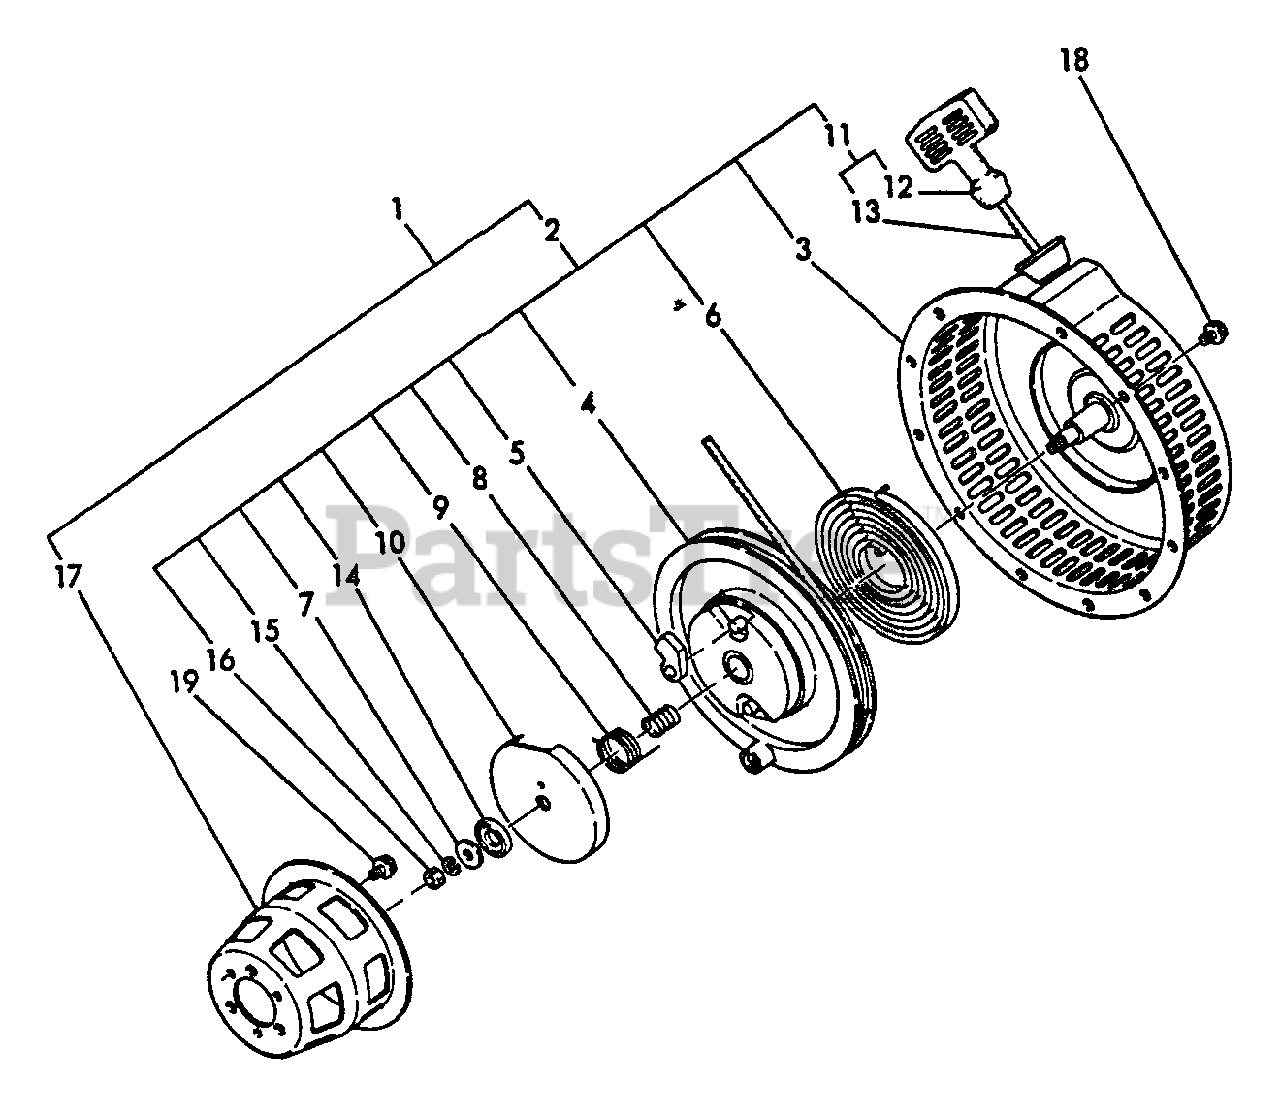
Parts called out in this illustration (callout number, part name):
1	STARTER ASSY, RECOIL
2	STARTER ASSY, RECOIL
3	CASE, STARTER
5	RATCHET
6	SPRING
7	WASHER, THRUST
8	SPRING, FRICTION
9	SPRING, RETURN
10	PLATE, FRICTION
11	STARTER ROPE ASSY
12	GRIP, STARTER
13	ROPE, STARTER
14	WASHER, THRUST
15	LOCKWASHER - 6
17	REEL, ROPE
18	BOLT - 6×8 -- PLATED
19	BOLT - 6×12 -- PLATED
